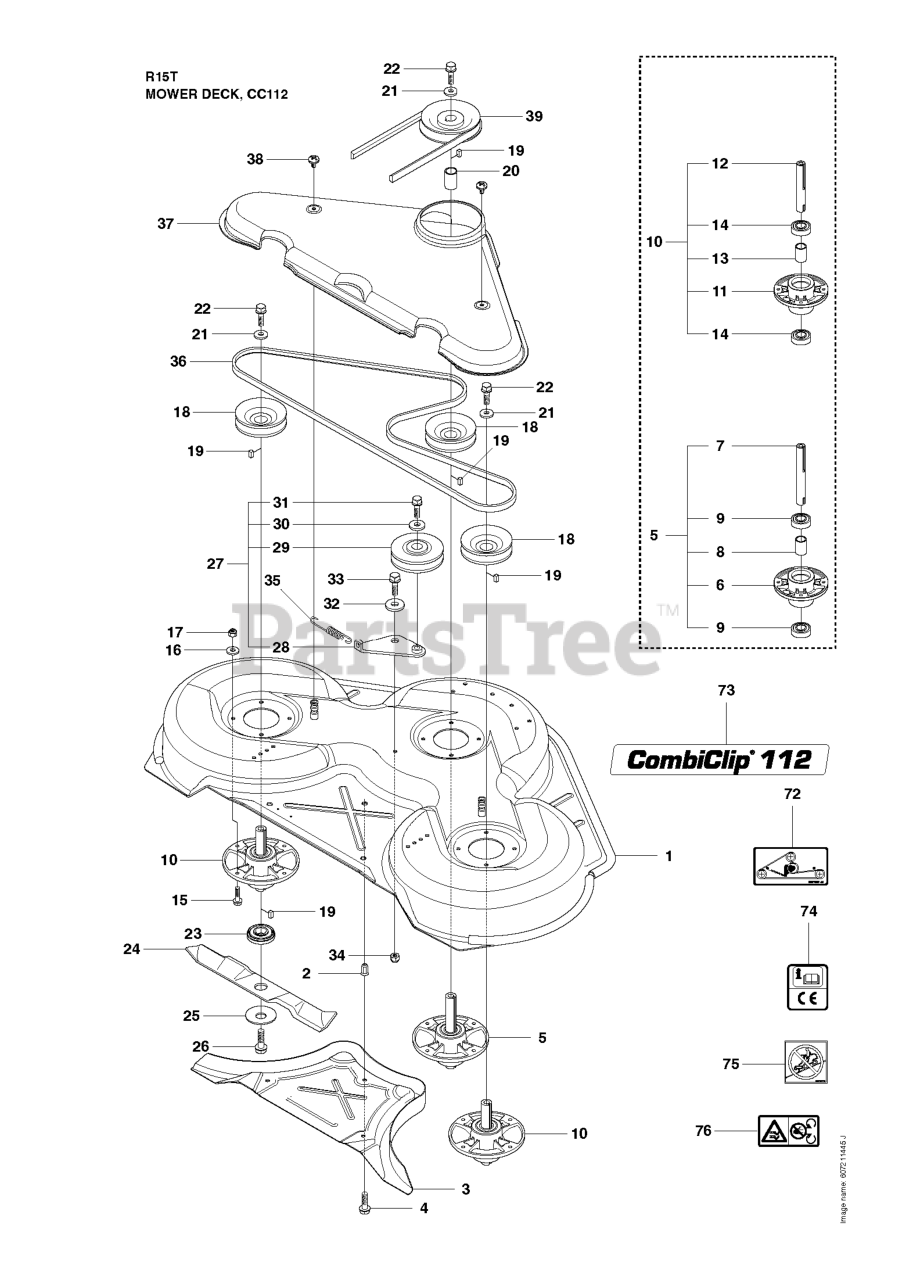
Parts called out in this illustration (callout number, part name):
1	CUTTING DECK
5	SPINDLE ASSY
6	BEARING HOUSING
10	RP SPINDLE ASSY
11	BEARING HOUSING
16	WASHER BRB 8.4X17
17	LOCKNUT M8
25	WASHER
27	BELT TENSIONER ASSY
28	BELT TENSIONING ARM
32	WASHER
34	LOCKNUT M8
36	BELT
37	BELT COVER
